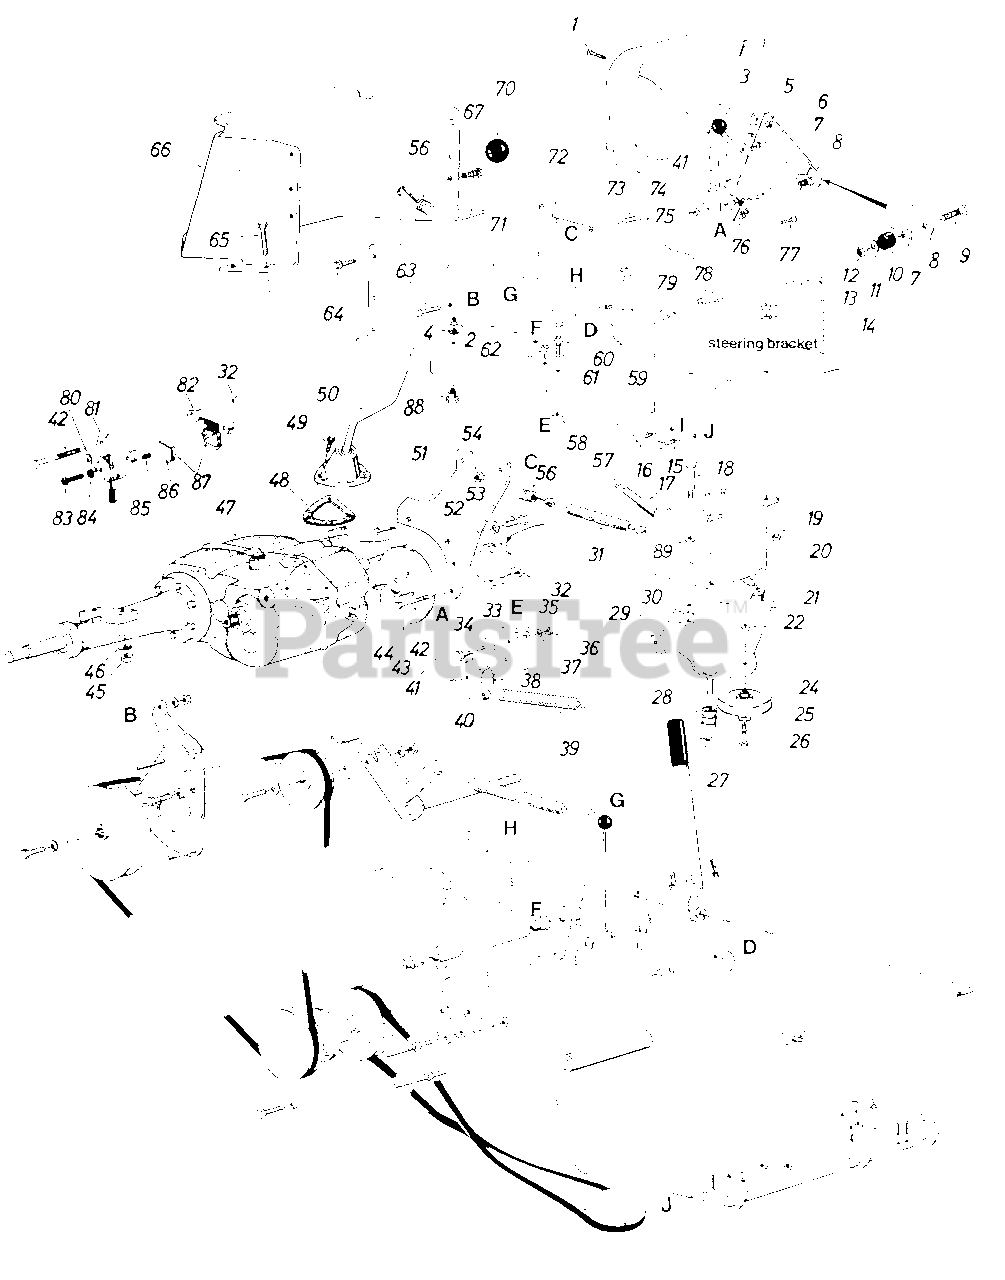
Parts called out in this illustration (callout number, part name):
1	Truss Mach. Scr. 1/4-20 x .50" Lg.
2	Hex Nut 1/4-20 Thd.
3	Knob Blade Clutch
4	L-Wash. 1/4 I.D.
5	Hex Sems Nut 1/4-20 Thd.
6	Push Cap 1/4" Rod
7	Blade Clutch Lever
8	Deck Clutch Control Brkt.
9	Hex Scr. 1/4-20 x 1.25" Lg.
10	Rubber Wash. .330 I.D. x .87
11	Fl-Wash. 1/4" I.D. x .75" O.D. x .057
12	Hex Cent. L-Nut 1/4-20 Thd.
13	Hex Nut 5/16-18 Thd.
14	L-Wash. 5/16" I.D.
15	Hex Bolt 3/8-16 x .62" Lg.
16	Shld. Bolt 1/2" Dia. x .335 Lg. 3/8-16
17	Convoluted Conduit .50 I.D. x4" Lg.
18	Shld. Bolt 7/16 Dia. x .16" 5/1 6-1 8
19	Hex Bolt 5/16-18 x 1.00" Lg.
20	Idler Mtg. Brkt. Deck
21	Idler Brkt. Ass'y.
22	Hex L-Nut 3/8-16 Thd.
24	4" "V" Idler Pulley
25	Fl-Wash. 3/8" I.D.
26	Hex Bolt 3/8-16 x 1.25" Lg.
27	Hairpin Cotter 5/16" Rod
28	Spacer
29	Hex Nut 5/16-18 Thd.
30	L-Wash. 5/16" Scr.
31	Ext. Spring Brake Rod
32	Hex Cent. L-Nut 3/8-16 Thd.
33	Disc Brake Caliper Ass'y.
34	Shld. Scr. 7/16" Dia. x .16" Lg. 5/16-18
35	Parking Brake Cam Mtg. Brkt.
36	Hex Nut 5/16-18 Thd.
37	L-Wash. 5/16" I.D.
38	Hairpin Cotter 5/16" Dia.
39	Ext. Spring Deck Control
40	Deck Control Pivot Brkt.
41	Deck Control Rod
42	Hex Bolt 3/8-16 x 2.50" Lg.
43	Hub & Disc Ass'y.
44	Hi-Pro Key 3/16 x 3/4" Lg.
45	Hex Nut 3/8-16 Thd.
46	L-Wash. 3/8" I.D.
47	Transaxle
51	Transaxle Support
52	L-Wash. 3/8" Scr.
53	Hex Scr. 3/8-16 x .75" Lg.
54	Hex L-Nut 3/8-16 Thd.
56	Ext. Spring Brake Return
57	Ext. Spring Deck Idler Return
58	Hex L-Nut 5/16-18 Thd.
59	Parking Brake Cam Mtg. Brkt.
60	Hex Nut 5/16-18 Thd.
61	Hex Bolt 5/16-18 x 1.5" Lg.
62	Hex Thd. Rolling Scr. 1/4-20 x.50" Lg.
63	Hex Bolt 3/8-16 x .75" Lg.
64	Hex AB-Tap Scr. 5/16 x .75" Lg.
65	Hex Scr. 3/8-16 x 1.50" Lg.
66	Hitch Plate
67	Hex Thd. Rolling Scr. 5/16-24 x .75" Lg.
70	Knob Transaxle
71	Side Panel Upper Frame R.H.
72	Side Panel Upper Frame L.H.
73	Hex Bolt 3/8-16 x .75" Lg.
75	Hex Nut #10-24 Thd.
76	Safety Switch
77	Truss Mach. Scr. #10-24 x .50" Lg.
78	Shld. Bolt 7/16" Dia. x .16" Lg. 5/16-18
79	Hex Thd. Rolling Scr. 1/4-20 x.50" Lg.
81	Housing with Lever & Pin
83	Pin: Adjuster
84	Nut
85	Pin: Actuator
86	Backing Plate
87	Lining
88	Shld. Bolt .375" Dia. x .180" Lg. 1/4-20 Thd.
89	Wave Washer
